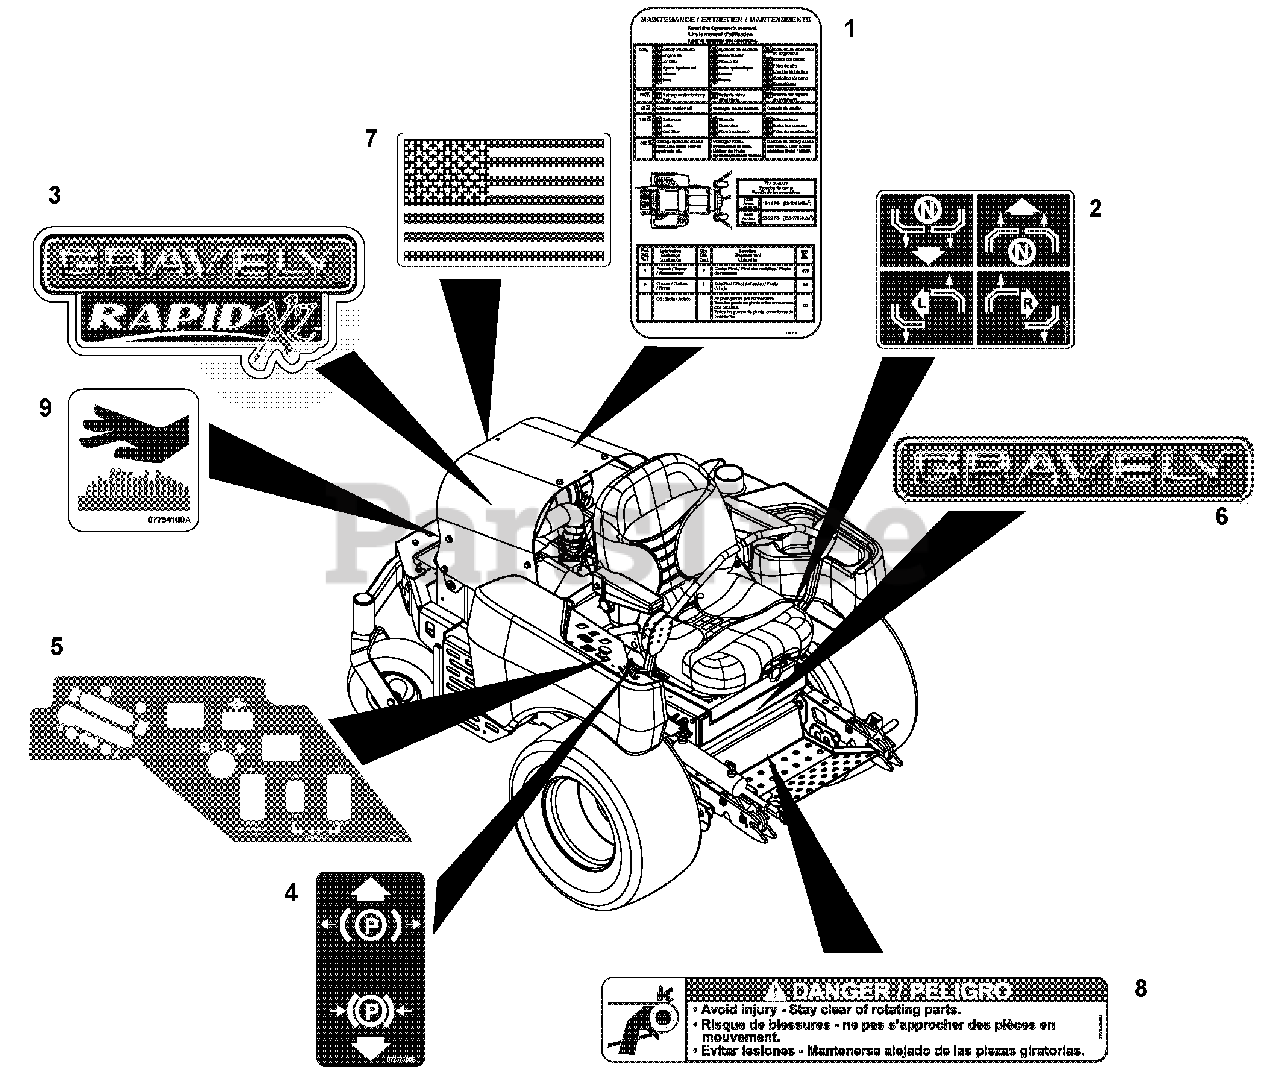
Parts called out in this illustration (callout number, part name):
1	Decal, Service Instructions Rapid XZ
2	Decal, Instructional Steering
3	Decal, Gravely Rapid XZHood
4	Decal, Parking Brake Lever
5	Decal, Control Panel Rapid XZ
6	Decal, Gravely Logo
7	Decal, American Flag
8	Decal, Danger
9	Decal, Hot Surface
